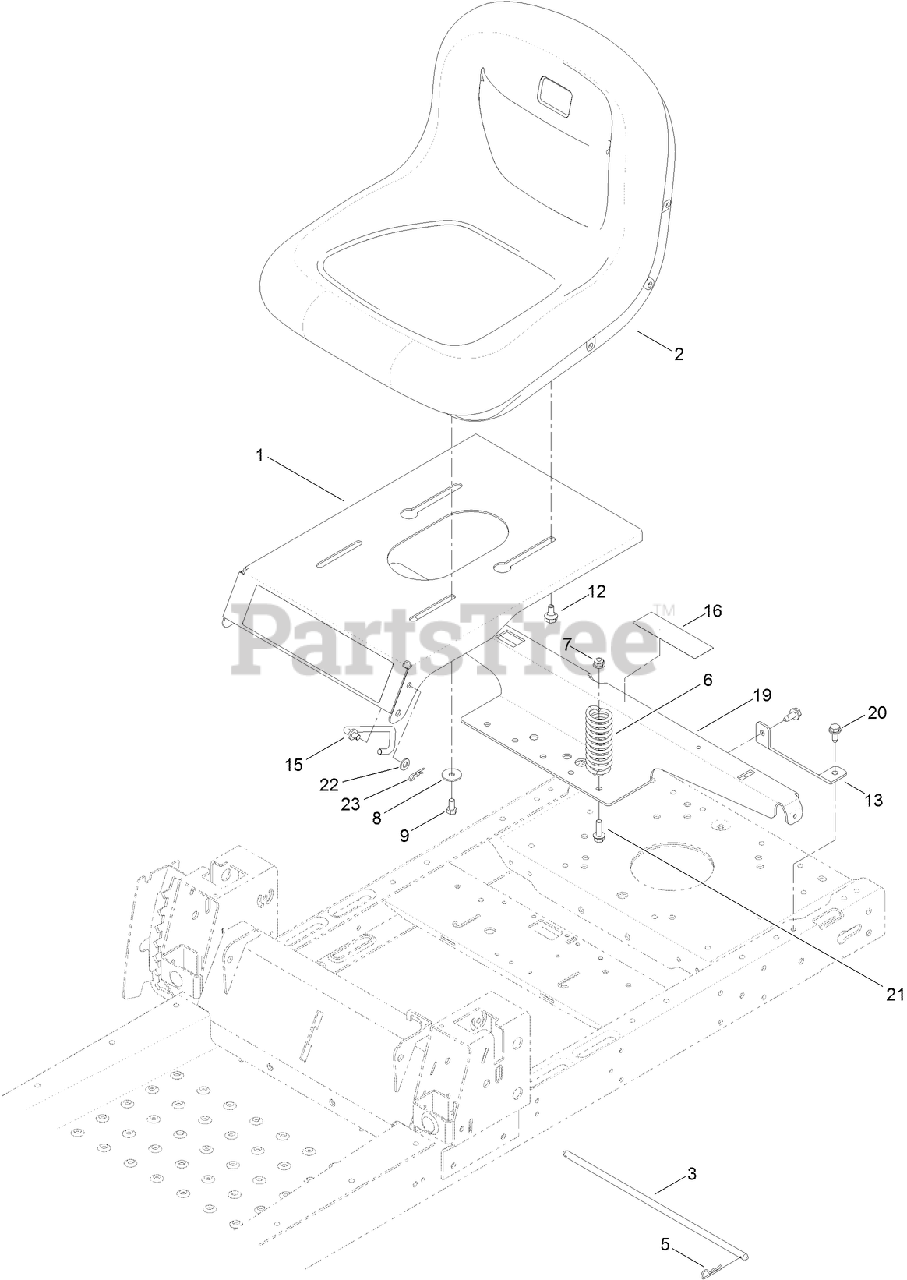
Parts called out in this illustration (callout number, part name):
2	SEAT-18 INCH
3	ROD-PIVOT, NARROW
5	PIN-COTTER
6	SPRING-COMPRESSION
7	NUT-HF, NI
8	WASHER-PIVOT
9	SCREW-HH
12	BOLT-SHOULDER,HFH
13	SUPPORT-TANK, REAR
15	STOP-SEAT
16	DECAL-SERVICE, CE
19	SUPPORT-POD
20	SCREW-HWHTF
21	SCREW-HHF
22	WASHER-PLAIN
